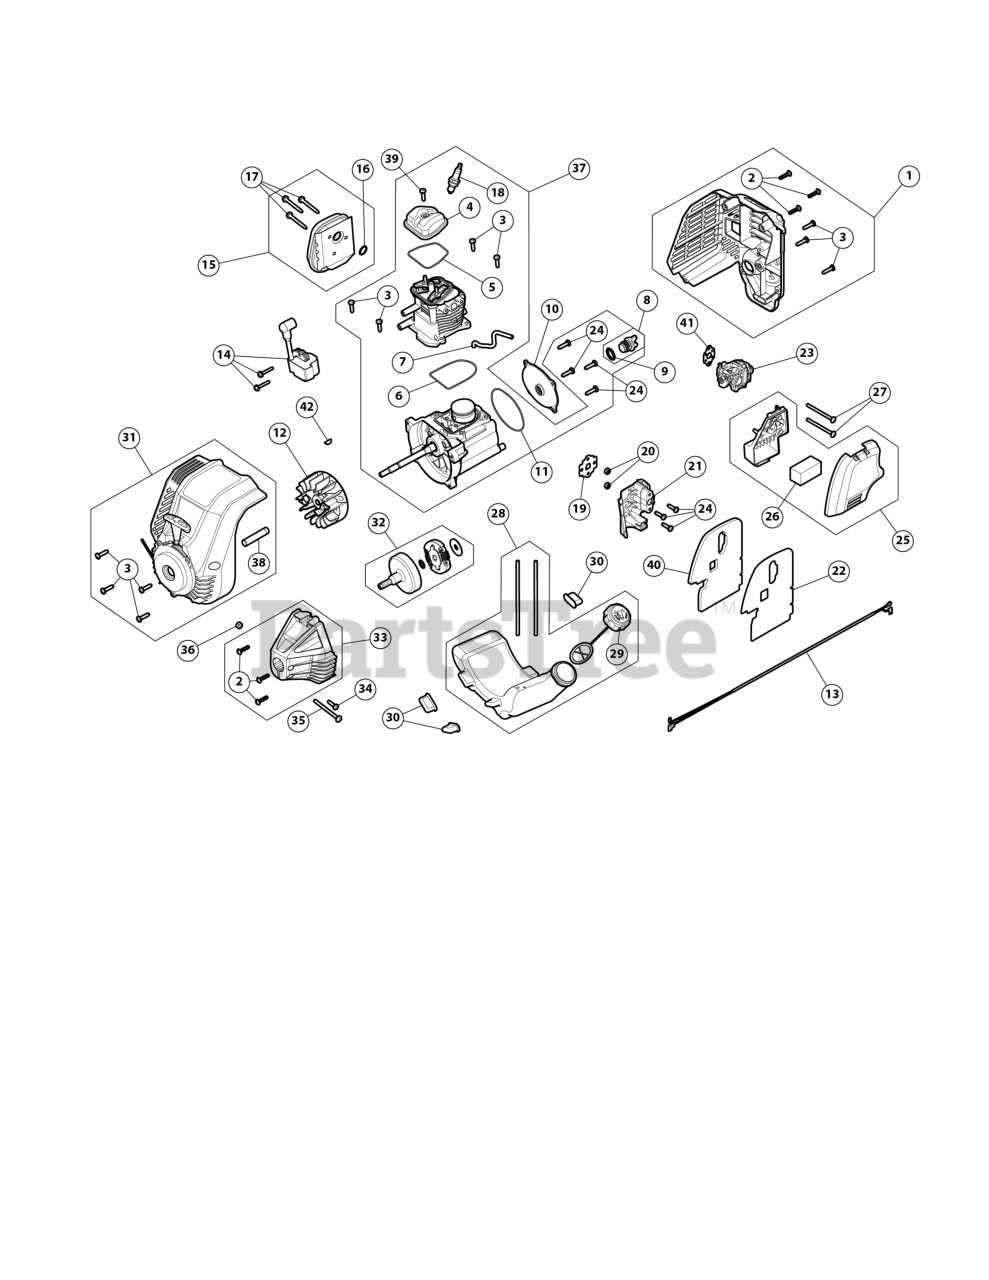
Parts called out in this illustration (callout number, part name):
1	REAR ENGINE COVER
2	SCREW 8-16 x 3/4
3	SCREW M5-0.8 x 19
4	ROCKER COVER
5	O-RING
6	O-RING CYL AC5
7	BREATHER HOSE
8	OIL PLUG
9	RING, OIL PLUG (AC
10	CRANKCASE COVER
11	O-RING CRNKCSE CVR
12	FLYWHEEL ASSEMBLY AC3.1
13	LEAD WIRES
14	MODULE ASSEMBLY
15	MUFFLER ASSEMBLY
16	GASKET/MUFFLER
17	SCREW M5 x 44MM
18	SPARK PLUG 4 CYCL
19	GASKET/INSULATOR
20	NUT 10-32
21	CARB INSULATOR
22	GASKET
23	CARBURETOR
24	SCREW, M5 X18
25	AIR CLEANER COVER
26	AIR FILTER
27	SCREW 10-32X2.5
28	FUEL TANK ASSEMBLY
29	FUEL CAP ASSEMBLY 43MM-6 W/O HOLE
30	FUEL TANK PADS
31	STARTER HOUSING
32	CLUTCH ASSEMBLY
33	CLUTCH COVER
34	SCREW, 8-32 x .312 P
35	SCREW
36	HEX NUT
37	SHORT BLOCK
38	SPACER :2.165"
39	SCR, VALVE COVER
40	HEAT SHIELD
41	CARBURETOR GASKET
42	WOODRUFF KEY #403-.125 x .375
